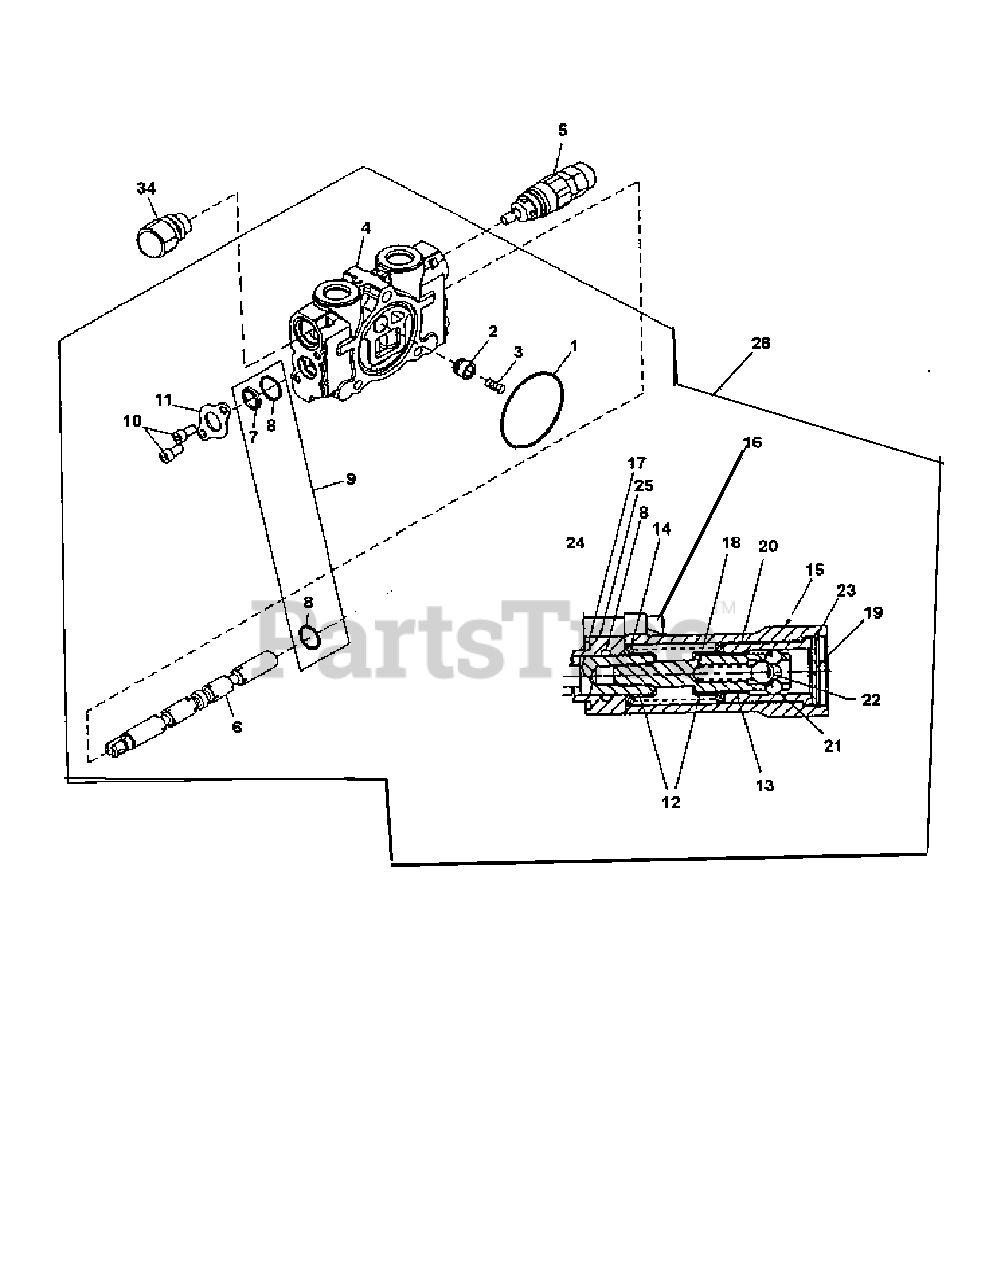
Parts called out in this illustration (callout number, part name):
1	O-RING
2	POPPET, LOAD CHECK
3	SPRING, LOAD CHECK
4	VALVE SECTION
5	RELIEF, WORK PORT 2650PSI
7	WIPER, SPOOL
8	O-RING SPOOL
9	SEAL KIT, MINOR
10	CAP SCREWS, SOCKET HEAD
11	PLATE, RETAINER
12	SEAT, SPRING
13	SCREW, SPRING SEAT
14	SPRING, SPOOL CENTERING
15	CAP, SPRING SPOOL
16	CAP SCREWS, SOCKET HEAD
17	O-RING
18	SPRING, DETENT
19	SPACER, CAP
20	SLEEVE, NON-DETENT
23	RING, RETAINING
24	SPACER, CAP SCREW
25	SPACER
26	VALVE SECTION ASSEMBLY
34	PLUG, SHUT OFF
